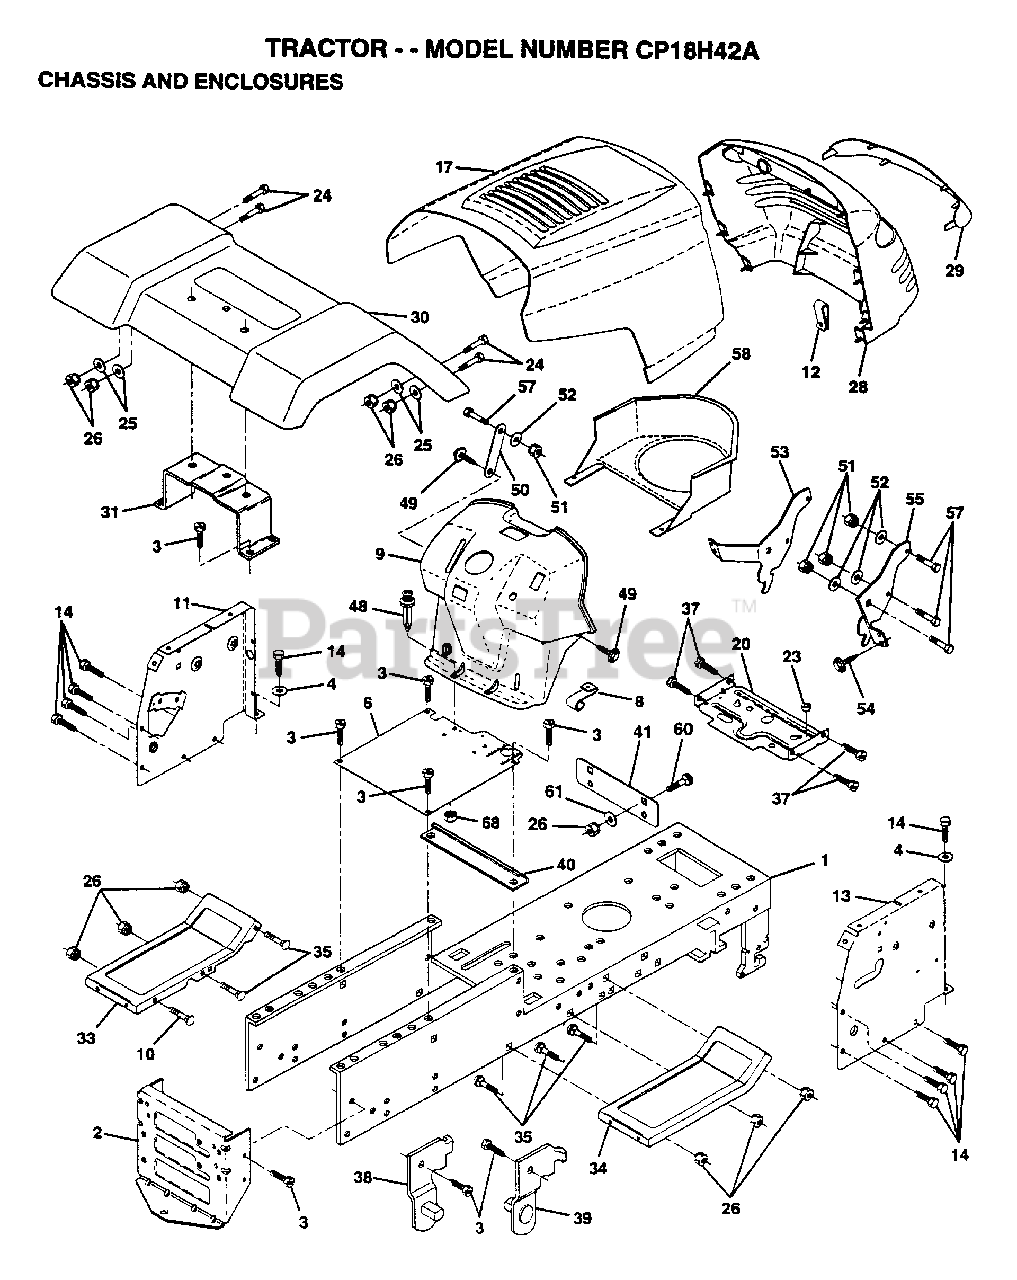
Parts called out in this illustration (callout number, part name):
1	CHASSIS.WLD.11GA
3	SCREW
4	WASHER
5	CLIP TINERMAN GRILLE P/L
8	"CLIP,INSULATOR"
11	PANEL.DASH.LH.
13	PANEL.DASH.RH
14	SCREW LT
17	HOOD.STL.PRV.LA
20	PLATE.MTG.BTRY.TK
24	BOLT
25	WASHER
26	NUT
28	GRILL.P/L.EURO.
29	LENS.P/L.EURO.
31	BRACKET SUPT FEND
33	FOOTREST.LH.LT/GT
34	FOOTREST.RH.LT/GT
35	BOLT
37	SCREW
38	BRACKET ASM LH
39	BRACKET ASM RH
40	SPACER FENDER LT
41	PLATE EXTEN FEND
48	RIVET.PUSH.PLATE
49	SCREW HEX CRT
50	BRACE SUPT DASH
51	NUT
52	WASHER
53	BRACKET.GRILLE.LH
55	BRACKET.GRILLE.RH
58	DUCT.AIR.B&S.18HP
60	BOLT
61	WASHER
68	NUT
